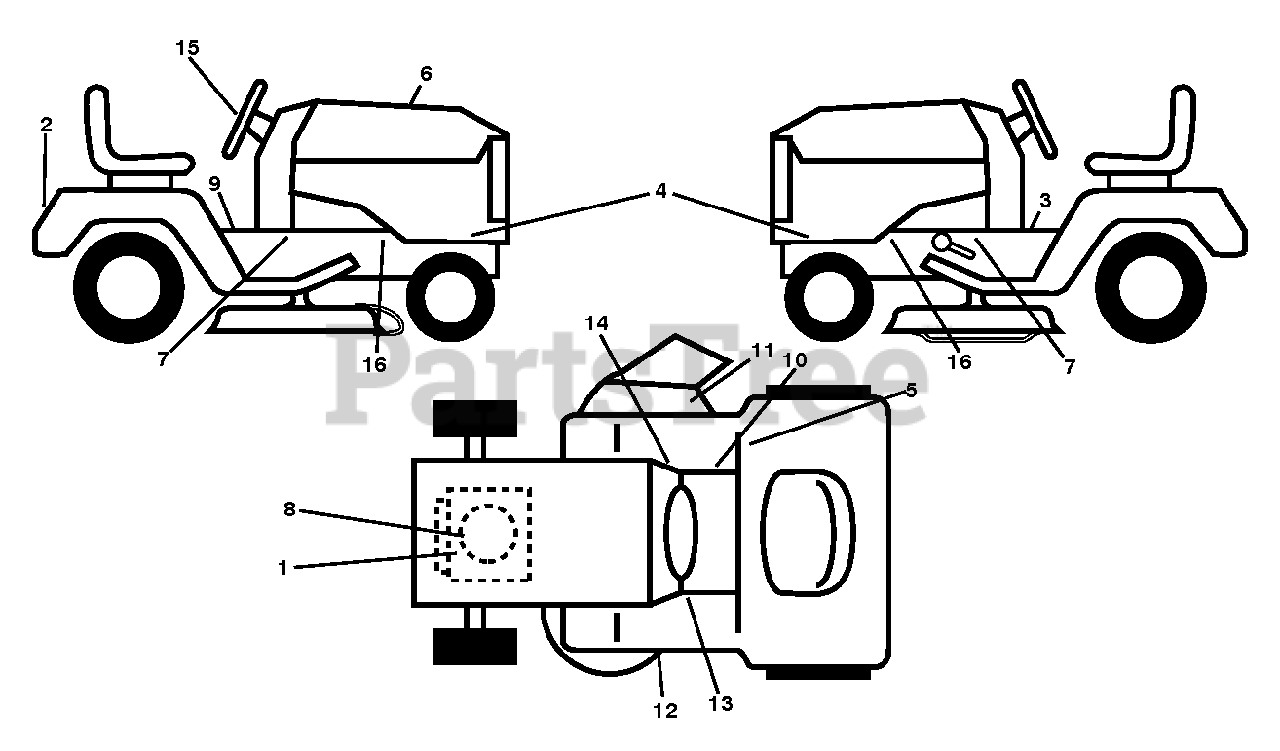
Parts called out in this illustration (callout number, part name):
9	DECAL BTRY SYMBOLS
11	DECAL.WARN.DFLECT/CTFINGR.SRD
14	DECAL PARK BRAKE
